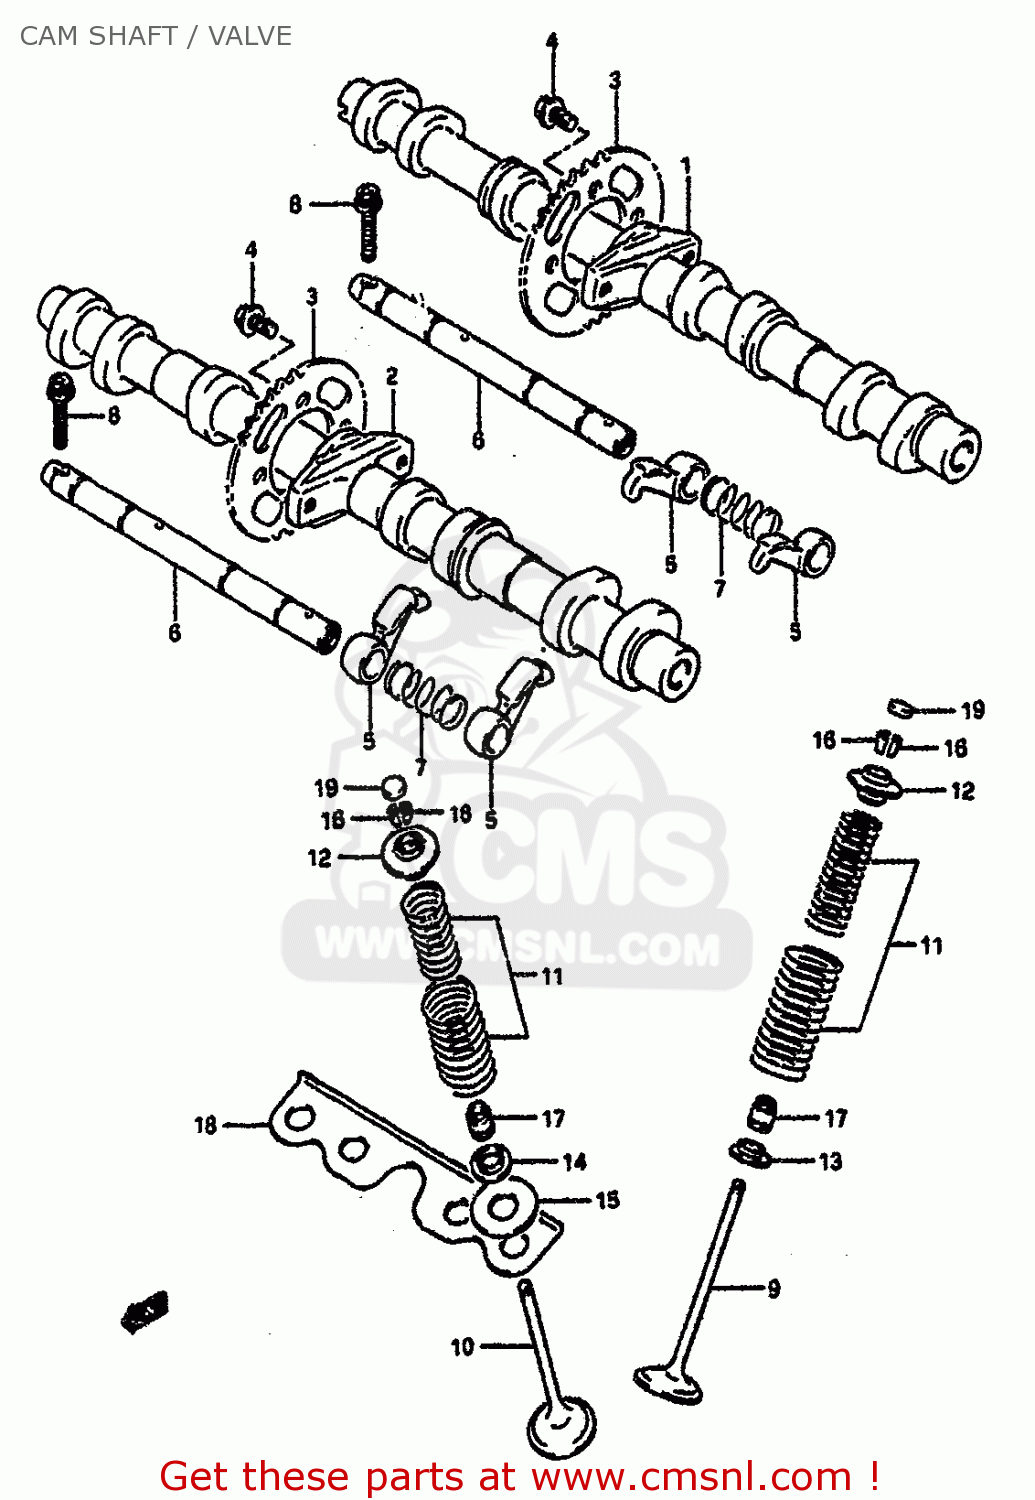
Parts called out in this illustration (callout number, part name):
1	CAMSHAFT,INTAKE
2	CAMSHAFT,EXHAUST
3	SPROCKET,CAMSHAFT
4	BOLT(7X11)
5	ARM,VALVE ROCKER
6	SHAFT,VALVE ROCKER
7	SPRING
8	BOLT
9	VALVE,INTAKE
10	VALVE,EXHAUST
11	SPRING SET,VALVE
12	RETAINER,VALVE SPRING
13	SEAT,VALVE SPRING
14	SEAT,VALVE SPRING
15	SEAT,VALVE SPRING EXH OUTER
16	COTTER VALVE
17	SEAL,OIL(5X10X9.7)
18	PLATE
19	SHIM,TAPPET(T:2.3)
21	CASE,TAPPET SHIM
